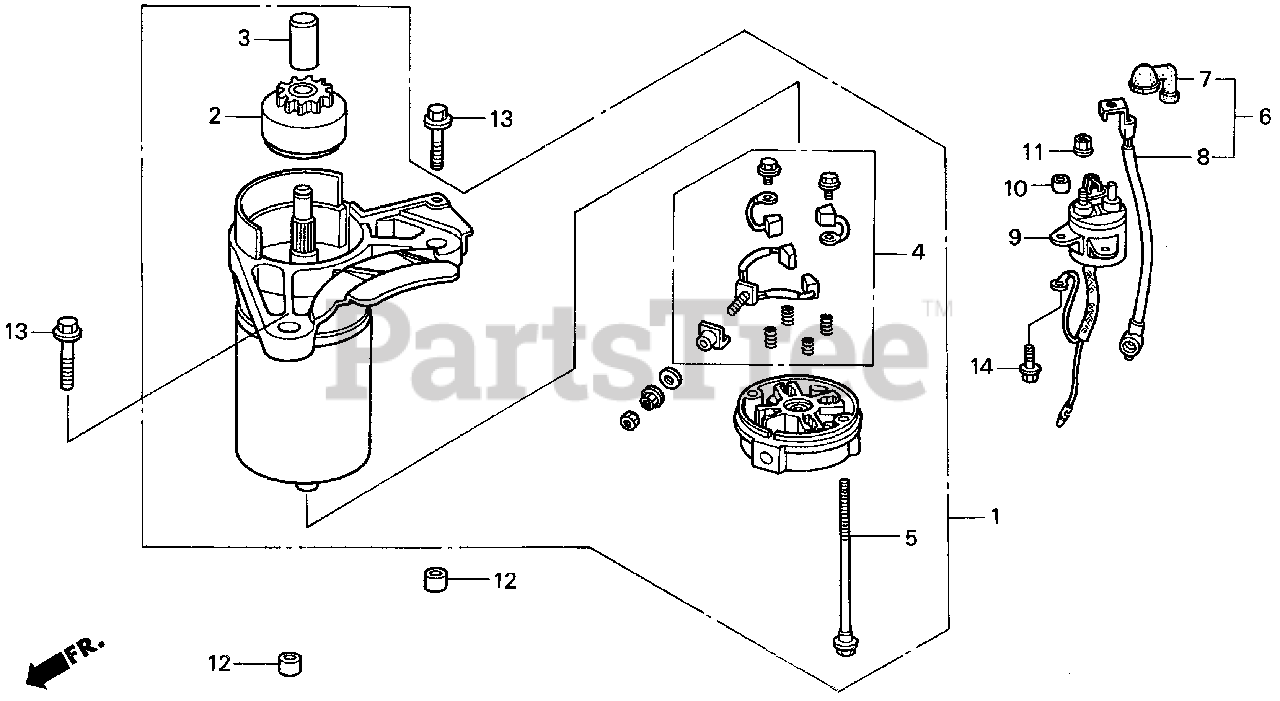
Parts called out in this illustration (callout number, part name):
1	MOTOR ASSY., STARTER
2	DRIVE ASSY.
3	STOPPER SET, PINION
4	BRUSH SET
5	BOLT, THROUGH
6	WIRE, MAGNET SWITCH
7	COVER, STARTER TERMINAL
8	COVER, MAGNETIC SWITCH TERMINAL
9	SWITCH ASSY., STARTER MAGNETIC
10	COLLAR, DISTANCE
11	NUT-WASHER (6MM)
12	PIN, DOWEL (10X12)
13	BOLT, FLANGE (8X35)
14	BOLT, FLANGE (6X25)
